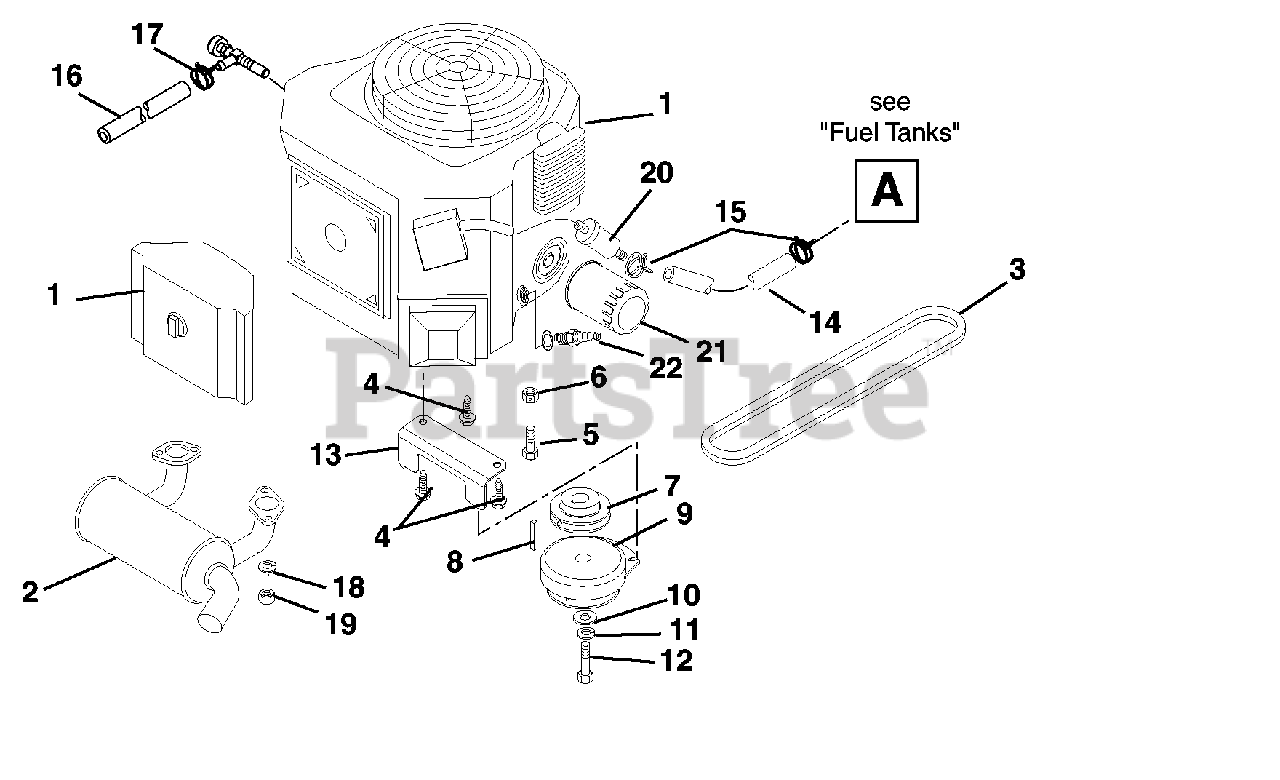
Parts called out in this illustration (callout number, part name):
1	Engine, 15HP FH451V Kawasaki
2	Muffler, Kawasaki
3	V-Belt HA 52 x .535 G48667
4	Screw, Tapping Hex Washer Head .38-16 x 1.00
5	Bolt, Hex .31-18 x 1.50 Grade 5
6	Nut, Locking Top Flange .31-18
7	Pulley, V 4.00 x 1.00
8	Key, Square .25 x .625 x .25 SAE 8630 OR SAE 1035
9	Clutch, Electric
10	Washer, Flat Steel .515 x 1.625 x .250
11	Washer, Locking .44 x .109
12	Bolt, Hex .44-20 x 2.50 Grade 5
13	Bracket, Clutch
14	Hose, Gas Line 35"- .25" I.D.
15	Hose, Clamp
16	Hose, .50 x 6.00
17	Clamp, .88 Diameter Hose
18	Washer, Lock .31 x .078 Regular
19	Nut, Hex M8-1.25
20	Fuel Filter, Kawasaki
21	Oil Filter, Kawasaki
22	Spark Plug, Kawasaki
